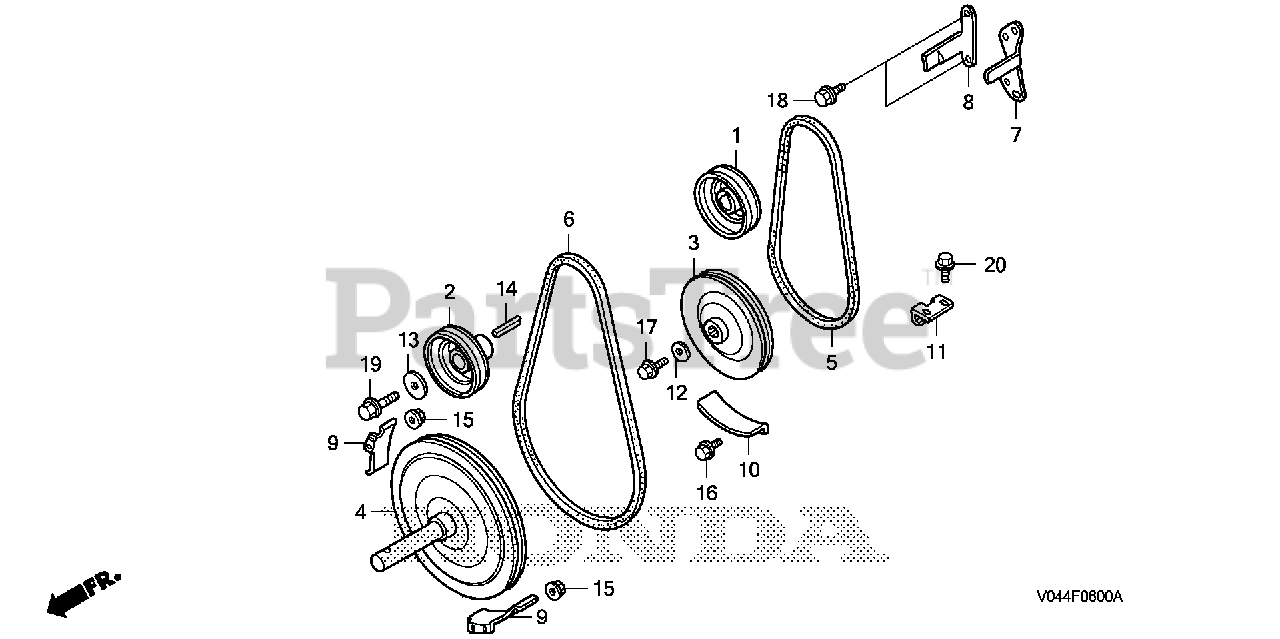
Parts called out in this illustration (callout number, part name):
1	PULLEY, WHEEL DRIVEN
2	PULLEY, AUGER DRIVE
3	PULLEY, WHEEL DRIVEN (133MM)
4	PULLEY, AUGER DRIVEN (198MM)
5	V-BELT (SA-27)
6	V-BELT (LB-33)
7	STOPPER, R. BELT (L. SIDE)
8	STOPPER, L. BELT (R. SIDE)
9	STOPPER, AUGER BELT
10	PROTECTOR, BELT (WHEEL)
11	GUIDE, BELT
12	WASHER, CAMSHAFT SIDE
13	WASHER, LOCK (8MM)
14	KEY (5MM)
15	NUT, FLANGE (6MM)
16	BOLT, FLANGE (6X12) Use up to Engine SN 1543277.
17	BOLT, FLANGE (6X16)
18	BOLT, FLANGE (8X16) Use from Engine SN 1000016.
19	BOLT, FLANGE (8X28)
20	BOLT, FLANGE (6X12) Use up to Engine SN 1543277.
20	BOLT, FLANGE (6X14)
